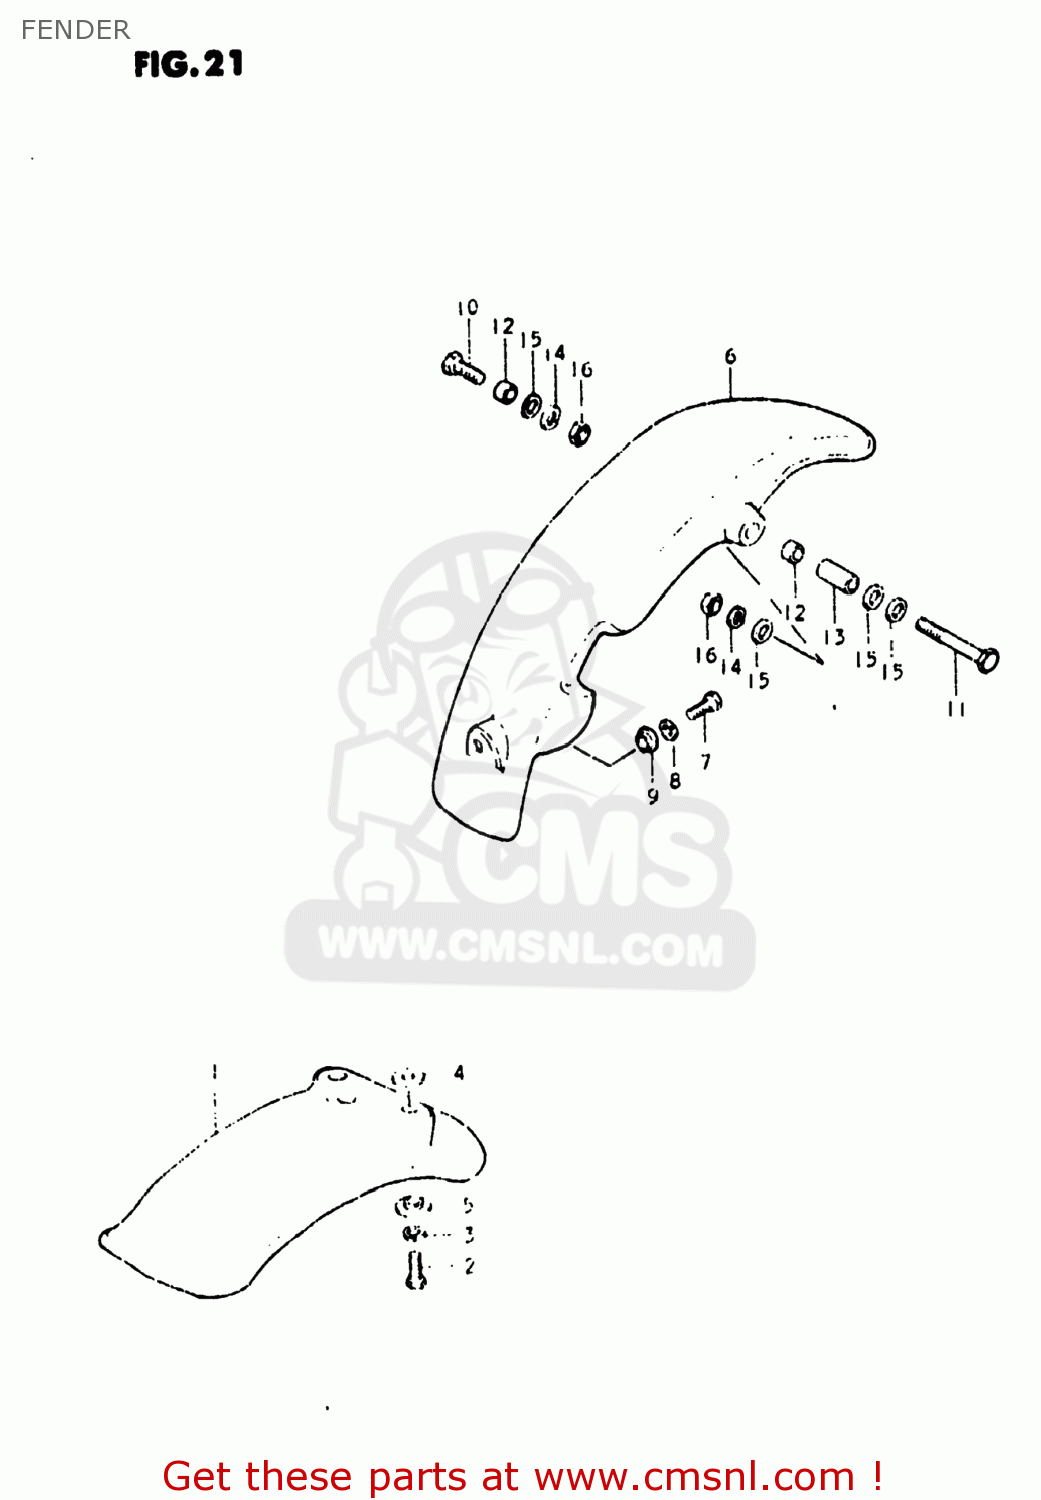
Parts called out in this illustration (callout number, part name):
1	FENDER,FRONT
2	BOLT
3	LOCK WASHER
4	WASHER(6.5X18X1)
5	WASHER
6	FENDER,REAR
7	BOLT
8	LOCK WASHER
9	WASHER
10	BOLT
11	BOLT 8X50
12	SPACER,RR FENDER RR
13	SPACER (8.2X12.5X23.5)
14	LOCK WASHER
15	WASHER
16	NUT
